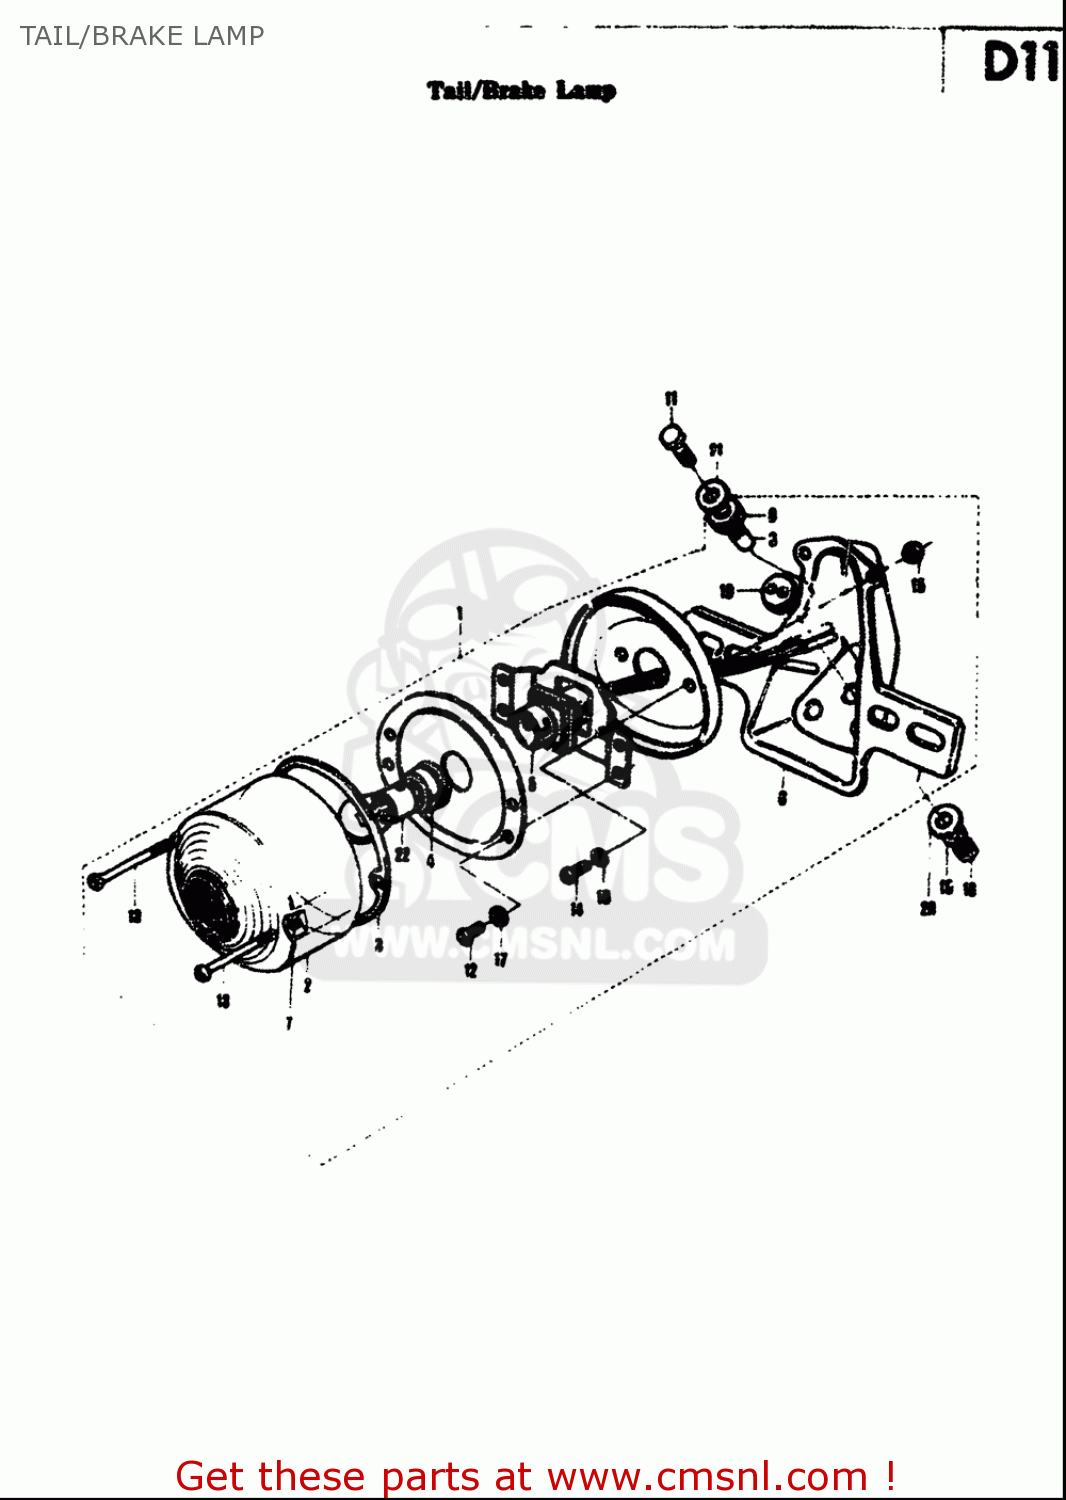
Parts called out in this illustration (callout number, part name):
2	LENS,RR COMBINATION LAMP
8	CUSHION
9	SPACER
10	GROMMET,REAR COMBINATION LAMP
11	BOLT
15	NUT
16	NUT
17	WASHER,LOCK
18	WASHER,LOCK
19	WASHER,LOCK
20	WASHER
21	WASHER(6.5X20X1.6)
22	BULB(12V23W)
